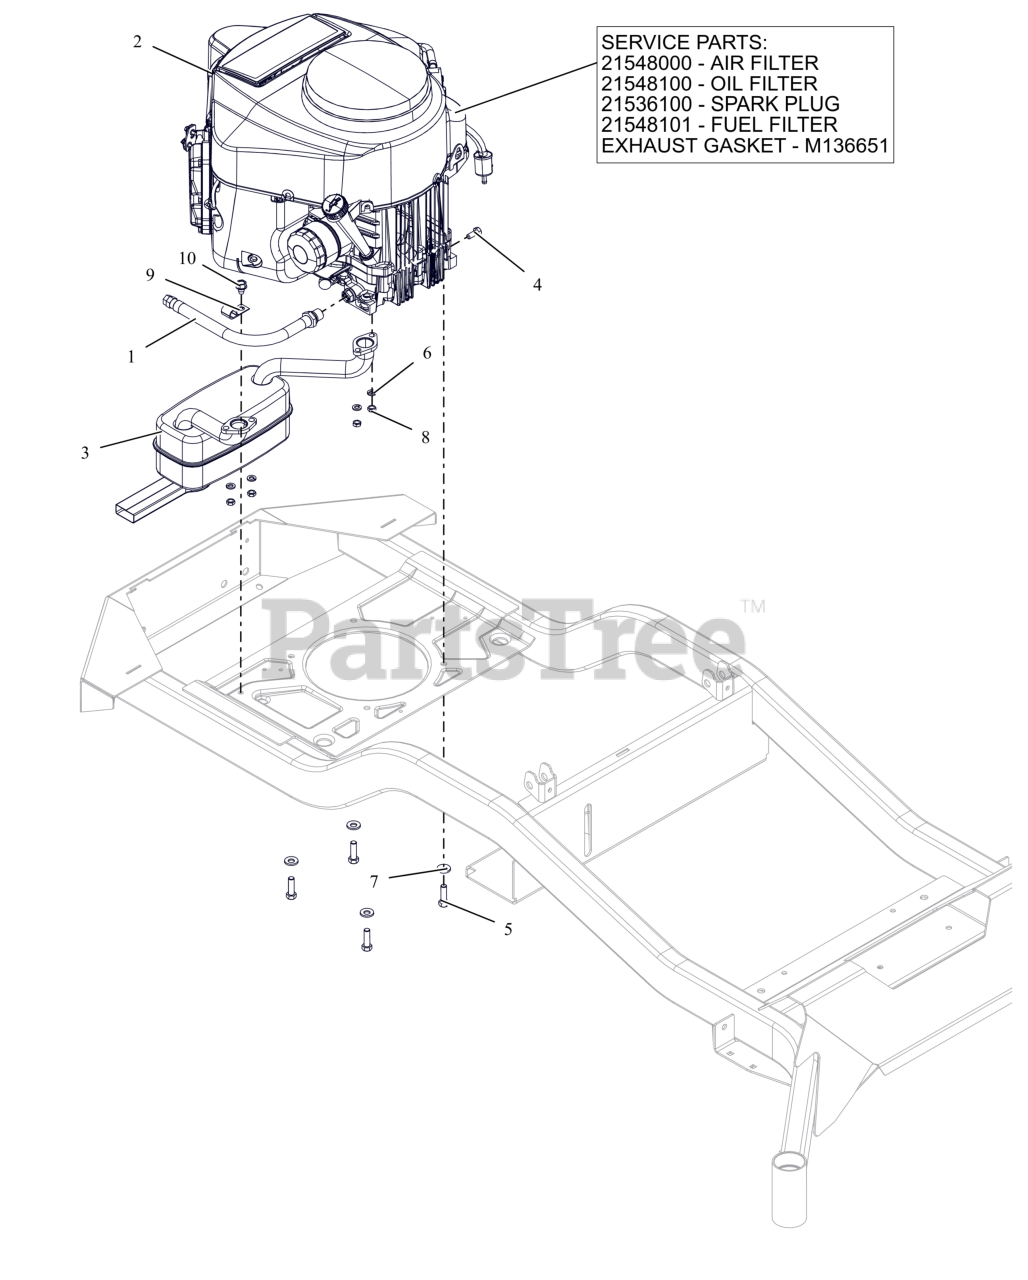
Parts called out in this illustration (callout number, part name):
1	HOSE, OIL DRAIN
2	ENGINE, KAWASAKI FR730 24HP
2	AIR FILTER, KAWASAKI FR
2	OIL FILTER, KAWASAKI FR
2	PLUG, SPARK
2	FUEL FILTER-KAWASAKI FR
2	GASKET, MUFFLER #
3	MUFFLER, KAWASAKI
4	BLT, HEX M8-1.25X20 G8.8 ZCC
5	BLT, HEX .38-16X1.25 G5 ZCC NT
6	WSHR,LK-REG .312X.078 ZCC
7	WASHER, 3/8" SPRING DISC
8	NUT, LK-CTR-JAM M8-1.25 GR8.8 ZC120
9	J-CLAMP
10	SCR,TAP .375-16X.50 HWH TR ZCC
